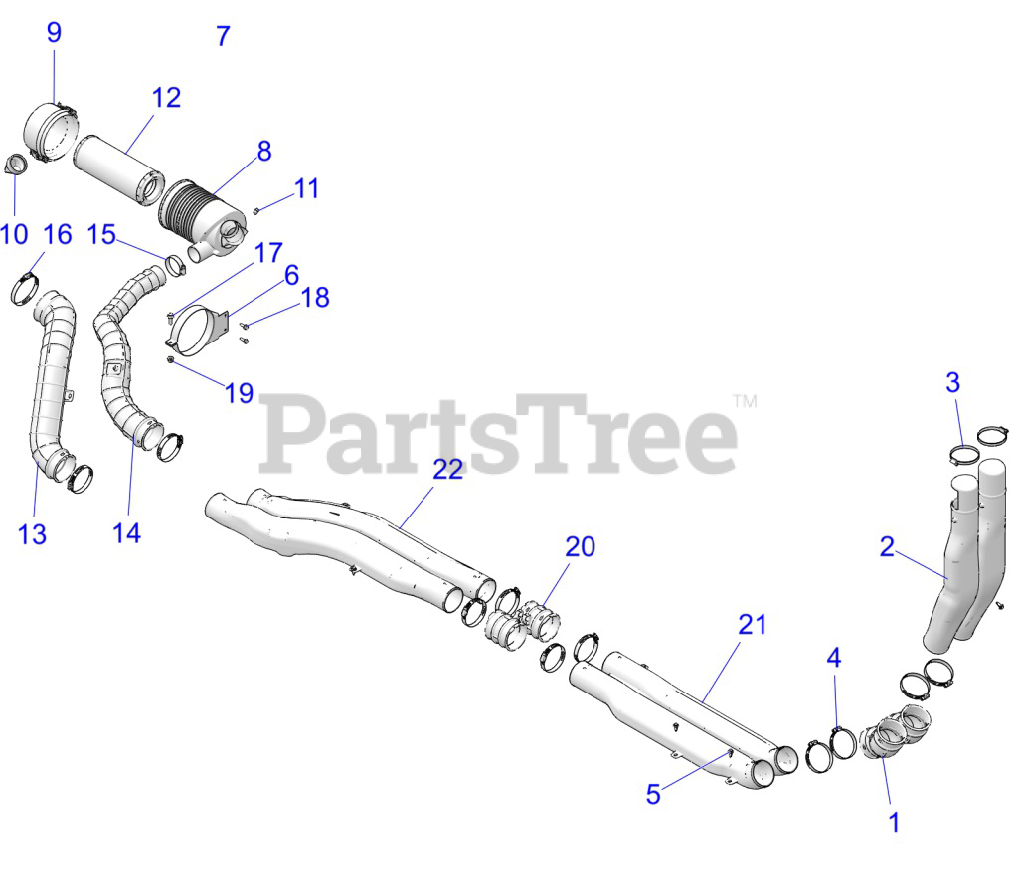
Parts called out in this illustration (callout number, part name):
1	HOSE-JOINT
2	DUCT-INTAKE-FRONT
3	CLAMP-BAND-NARROW 70-90MM
4	CLAMP-HOSE SLOTTED-75-90 DIA
5	RIVET-TUFLOK-.315-.325X.787 (5
6	WELD-MOUNT-AIRBOX
7	ASM-AIR INTAKE
8	ASM., AIRBOX, MAIN
9	ASM-LID-AIRBOX
10	VALVE-AIRBOX
11	PLUG-AIRBOX
13	HOSE-CLUTCH INLET TO TUNNEL
14	HOSE-INTAKE- PRE-FILTER
14	HOSE-INTAKE,PRE-FILTER
15	CLAMP- HOSE- S.S.(10)
16	CLAMP-HOSE SLOTTED- 89-100 DIA
17	BOLT-M8X1.25X25-HXFLG-OLIVE D
18	SCR-TXTH-M6X1.0X25 RIE
19	NUT-M8X1.25-FLG-NYLOC-OLIVE D
20	HOSE-INTAKE-DUCT
21	DUCT-TUNNEL-FRONT
22	DUCT-TUNNEL-REAR
